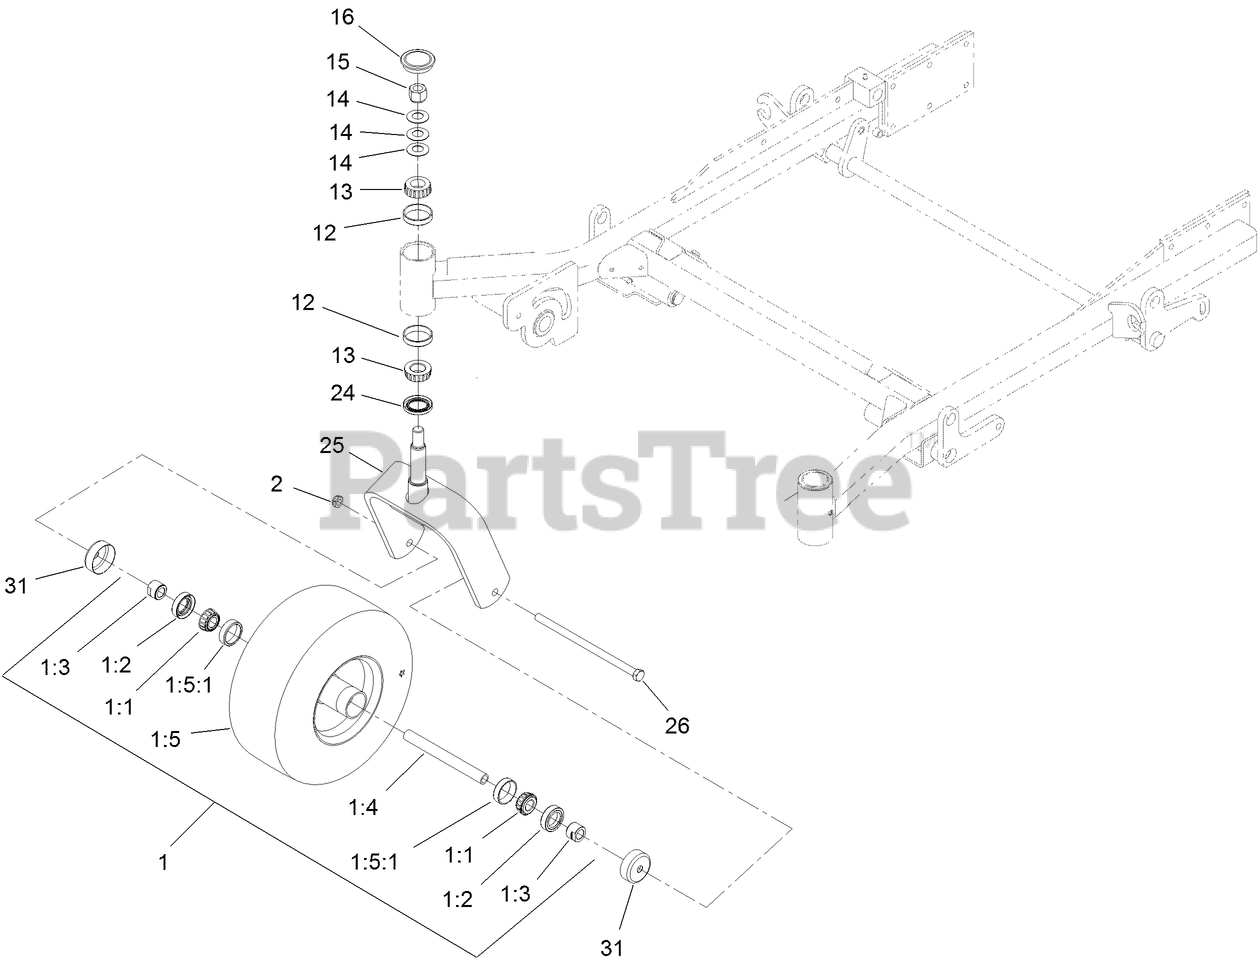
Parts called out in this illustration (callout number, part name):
1	WHEEL AND BEARING ASM
1:1	BEARING-CONE, TAPER
1:2	SEAL-CASTER
1:3	SPACER-NUT
1:4	AXLE CASTER ASM
1:5	HUB and BEARING ASM
1:5:1	BEARING-CUP
2	NUT-HEX
12	BEARING-CUP, TAPERED
13	BEARING-CONE, TAPERED
14	WASHER-BELLVILLE
15	NUT-LOCK, NI
16	CAP-GREASE
24	SEAL-GREASE
26	SCREW-HH
31	GUARD-SEAL
